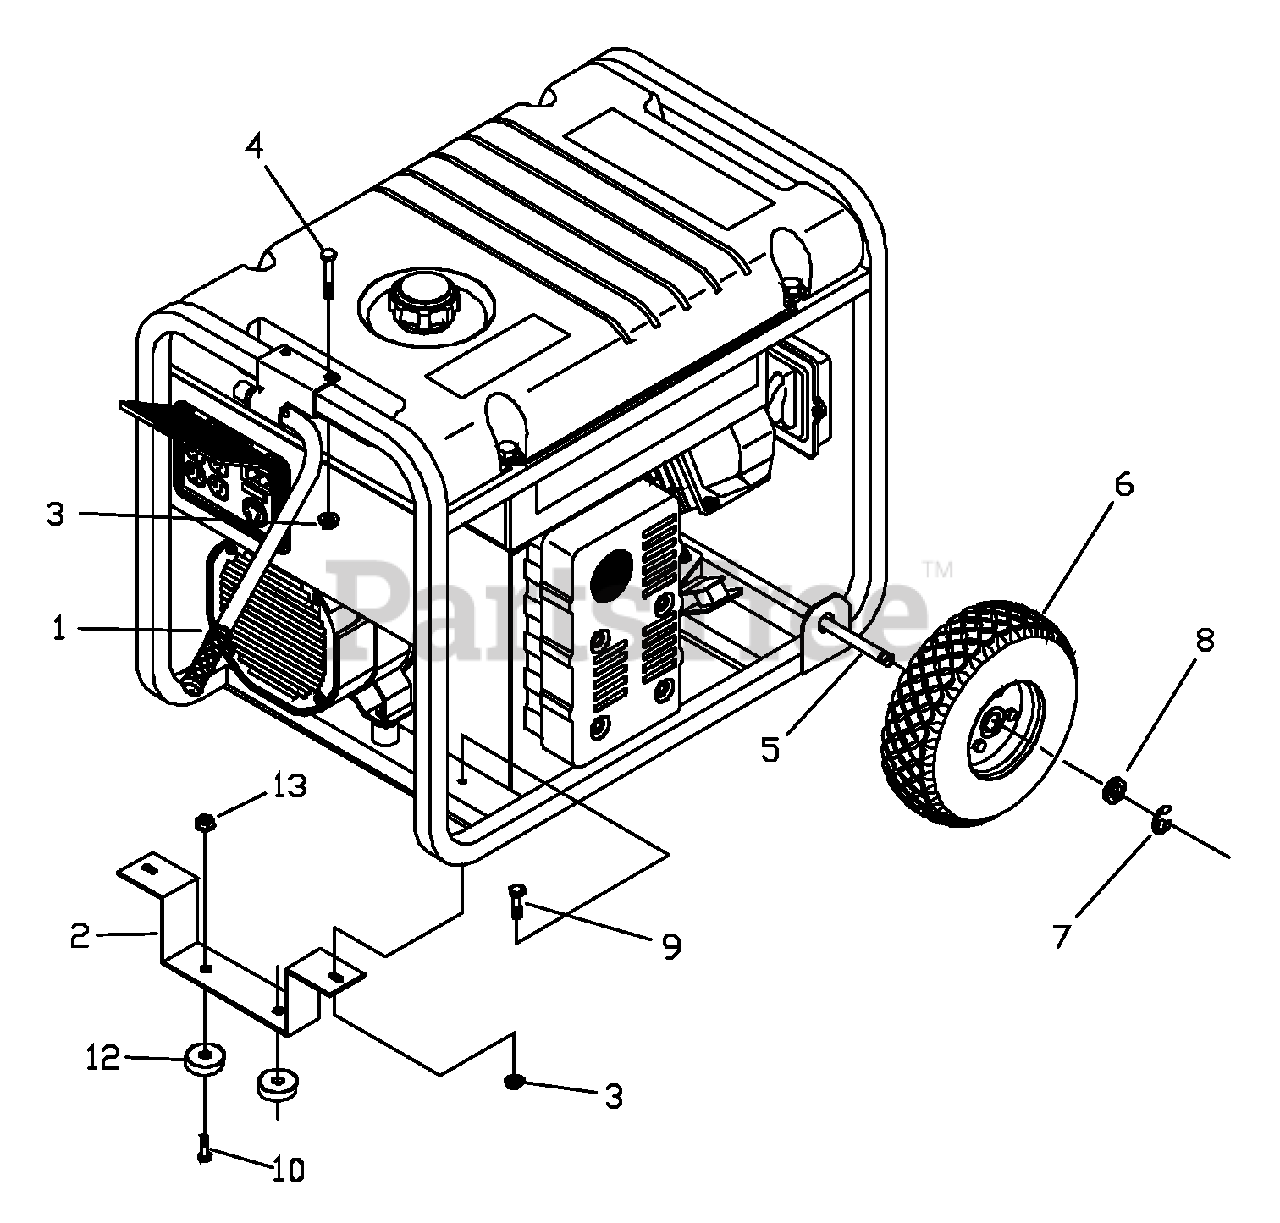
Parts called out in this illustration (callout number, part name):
1	ASSY, Handle
2	LEG, Mounting
3	NUT, Locking Hex M8 - 1.25
4	HHCS, M8 - 1.25 x 45
5	AXLE, 5/8" x 23.62"
6	WHEEL, 10" Diameter
7	E-RING
8	WASHER, Flat, 5/8"
9	HHCS, M8 - 1.25 x 20
10	HHCS, 1/4 - 20 x 1.00 Lg
12	VIBE MOUNT, with Washer
13	NUT, 1/4 - 20 Serrated Lock
